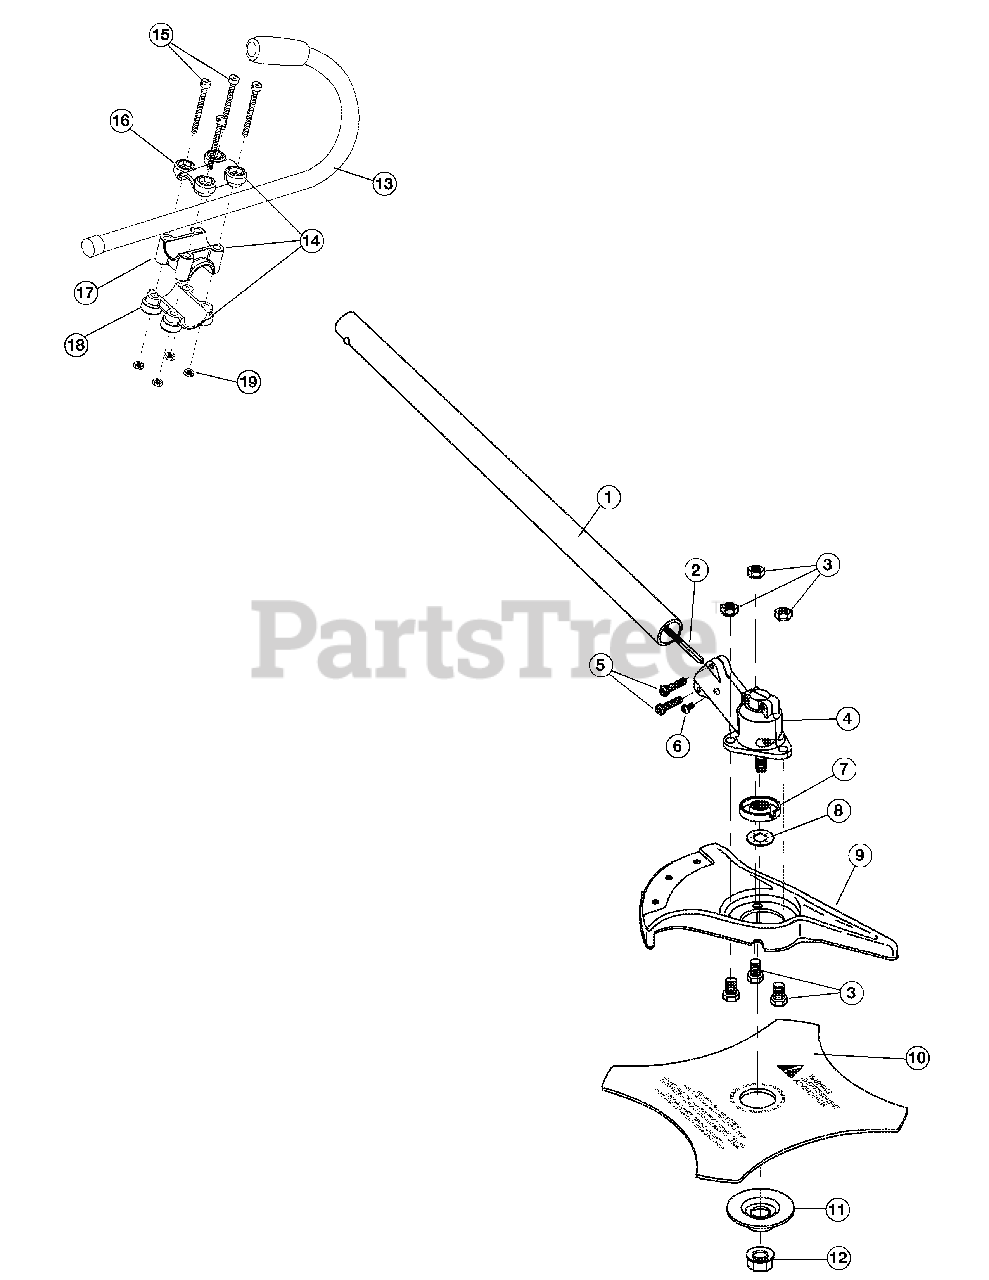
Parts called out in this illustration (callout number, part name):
1	Lower Drive Shaft Housing Assembly
2	Lower Flexible Drive Shaft
3	Shield Mount Screw Assembly
4	2 piece Gearbox Assembly (includes 28-30)
5	Gearbox Mounting Hardware
6	Anti-Rotation Screw
7	Blade Driver
9	Blade Shield/Shield Mount
10	4-Tooth Blade
11	Retaining Washer
12	Nut
13	J-Handle Assembly
14	Handle Bracket Assembly (includes 13-18)
16	Upper Handle Clamp
17	Middle Handle Clamp
18	Lower Handle Clamp
